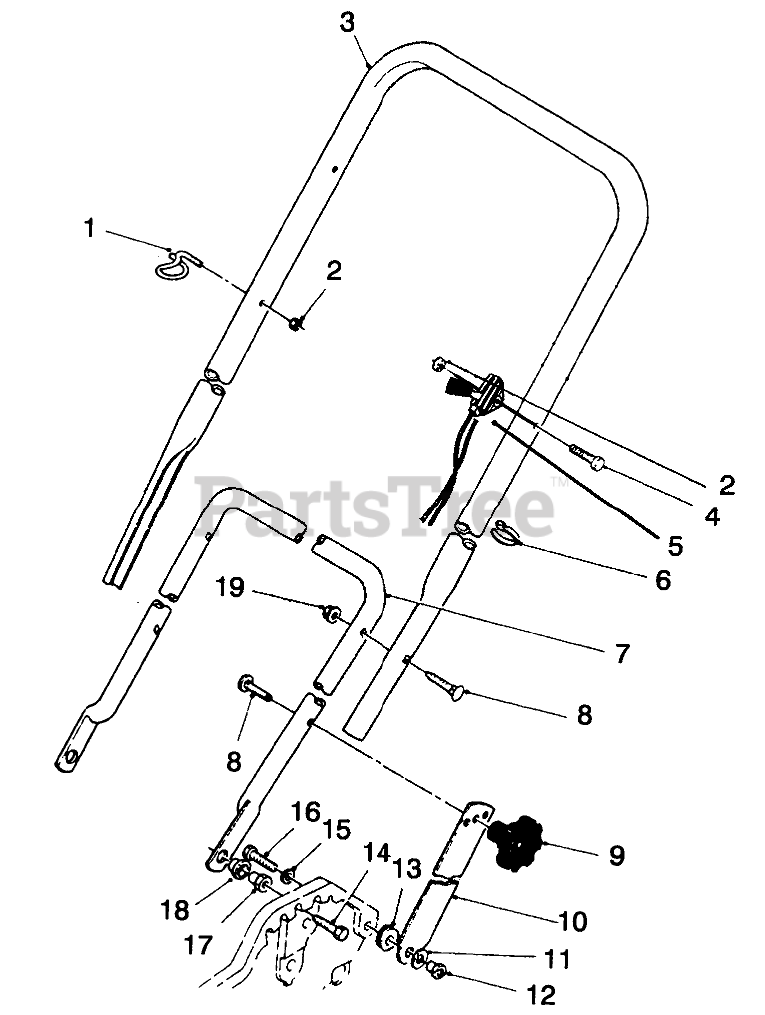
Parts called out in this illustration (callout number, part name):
1	ROPE GUIDE
2	NUT-LOCK, NI
3	HANDLE (DIPPED)
4	SCREW-HANDLE
5	THROTTLE CONTROL
6	TIE-CABLE
7	LOWER HANDLE(CROM)
8	SCREW
10	HANDLE LATCH
11	WASHER
12	POST-MOUNTING, LINKAGE
13	GROMMET
14	SCREW-HH
15	WASHER-LOCK
16	SCREW-HH
17	HANDLE PIVOT NUT
18	FLANGE BUSHING
19	NUT-LOCK, NI
